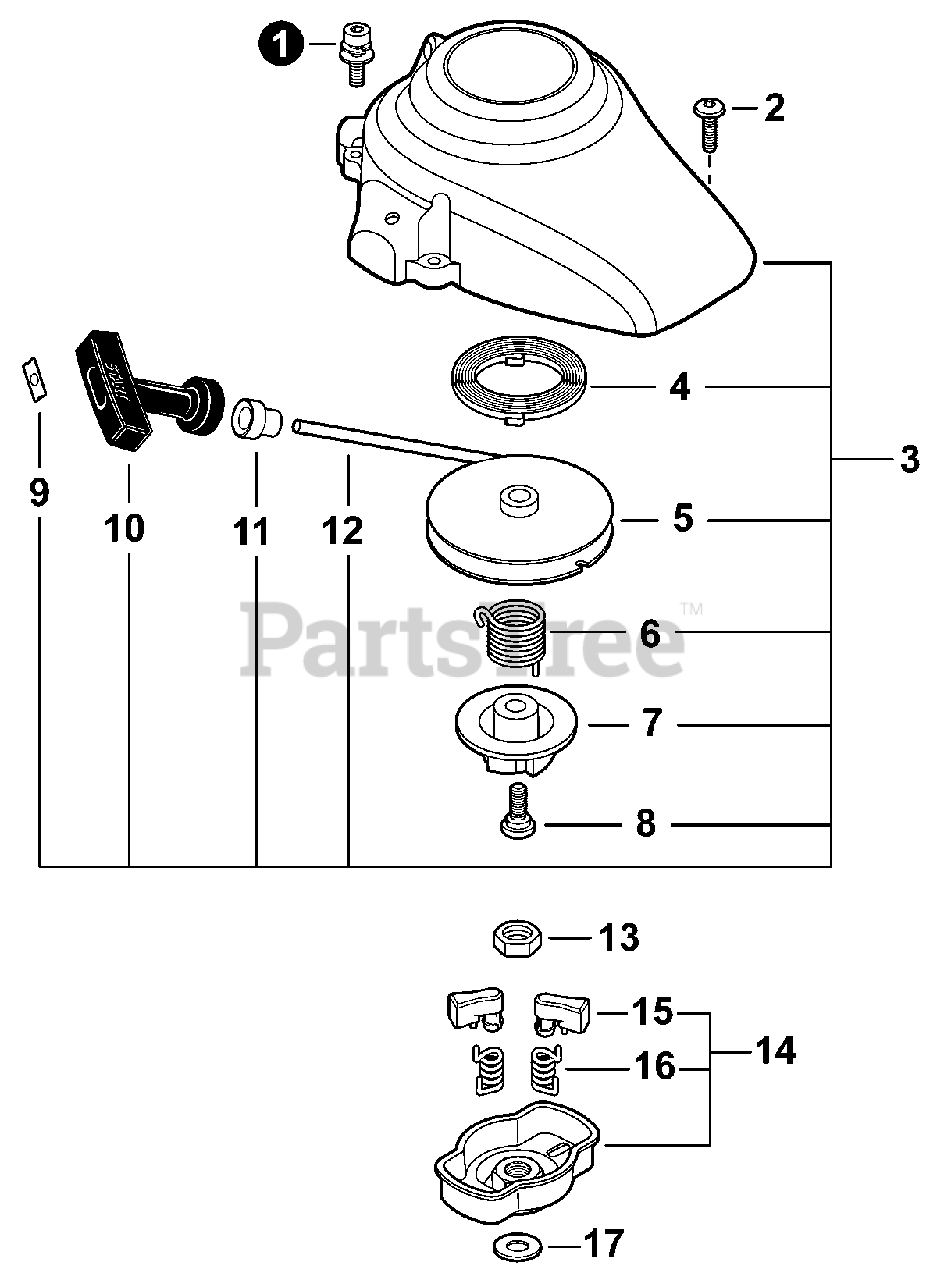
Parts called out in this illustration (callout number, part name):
1	BOLT 4×16
2	BOLT 4×12
3	STARTER ASSY, RECOIL
4	SPRING, RECOIL
5	REEL, ROPE
6	SPRING, TORSION
7	PAWL CATCHER
8	SCREW
9	RETAINER, ROPE
10	GRIP, STARTER
11	GUIDE, ROPE
12	ROPE, STARTER 3×700
14	PULLEY ASSY, STARTER
15	PAWL, STARTER
16	SPRING, RETURN
17	WASHER 8.5×16×1.2
